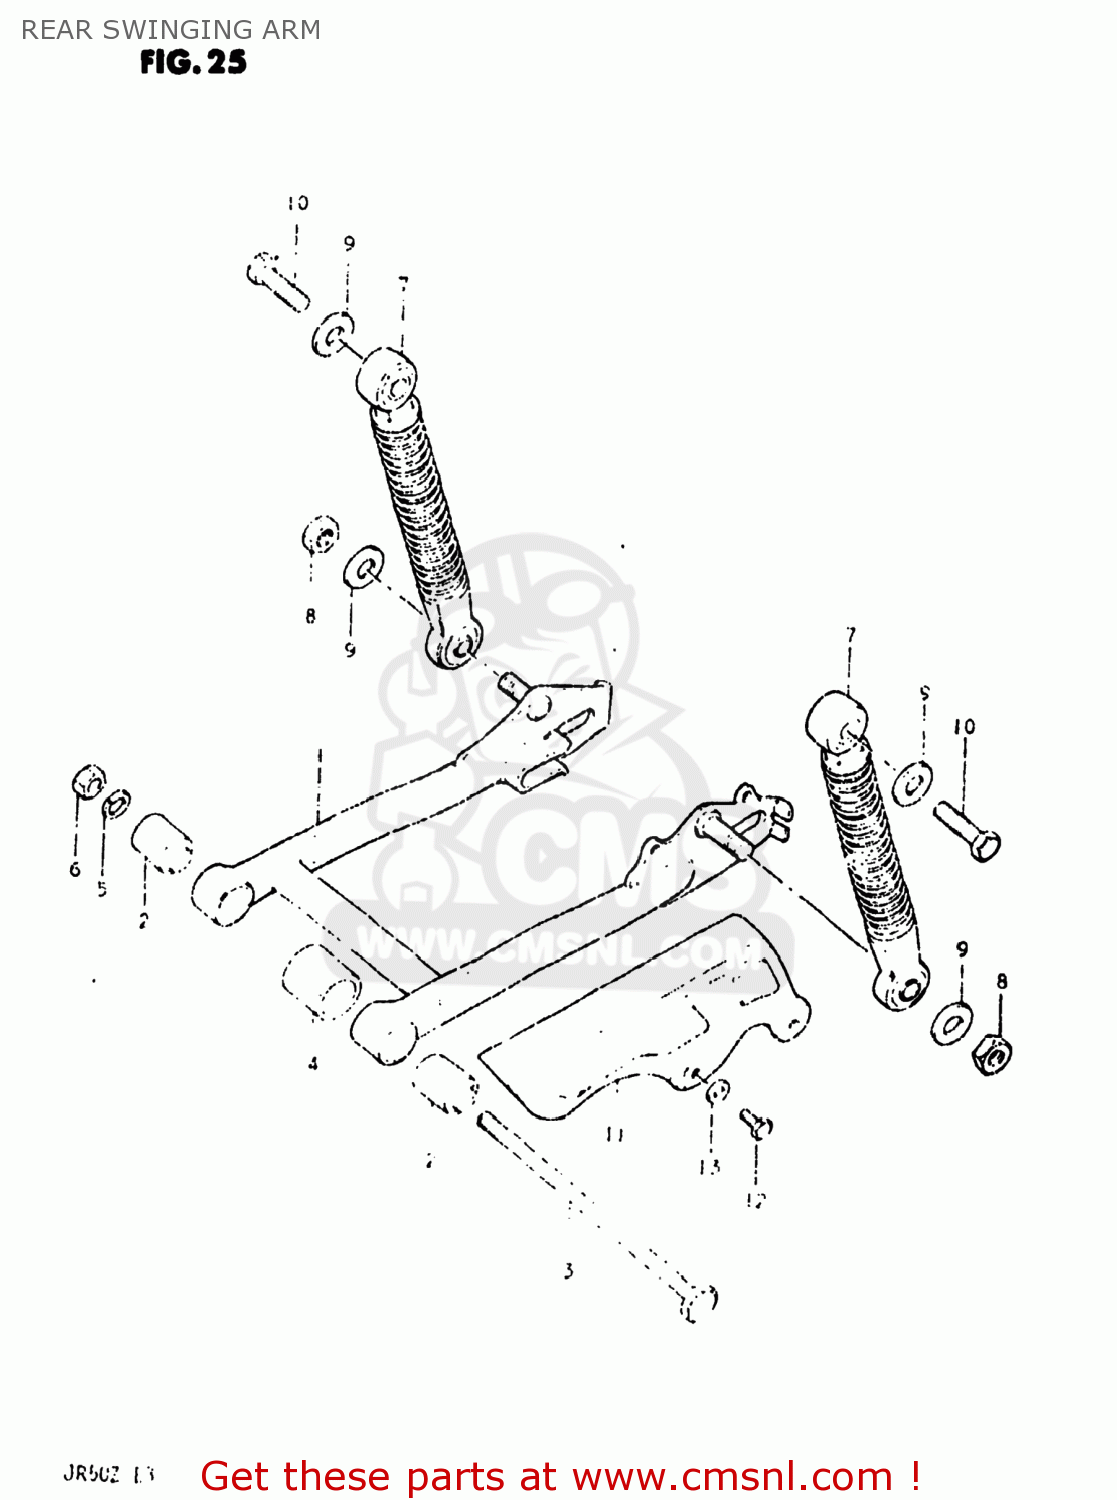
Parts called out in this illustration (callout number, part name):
1	SWING ARM ASSEMBLY,REAR
2	BUSH
3	SHAFT,RR SWINGINGARM PIVOT
4	CUSHION
5	LOCK WASHER
6	NUT
7	ABSORBER ASSY,RR SHOCK
8	NUT
9	WASHER
10	BOLT,M10X1.25X
11	CASE,CHAIN
12	BOLT
13	LOCK WASHER
